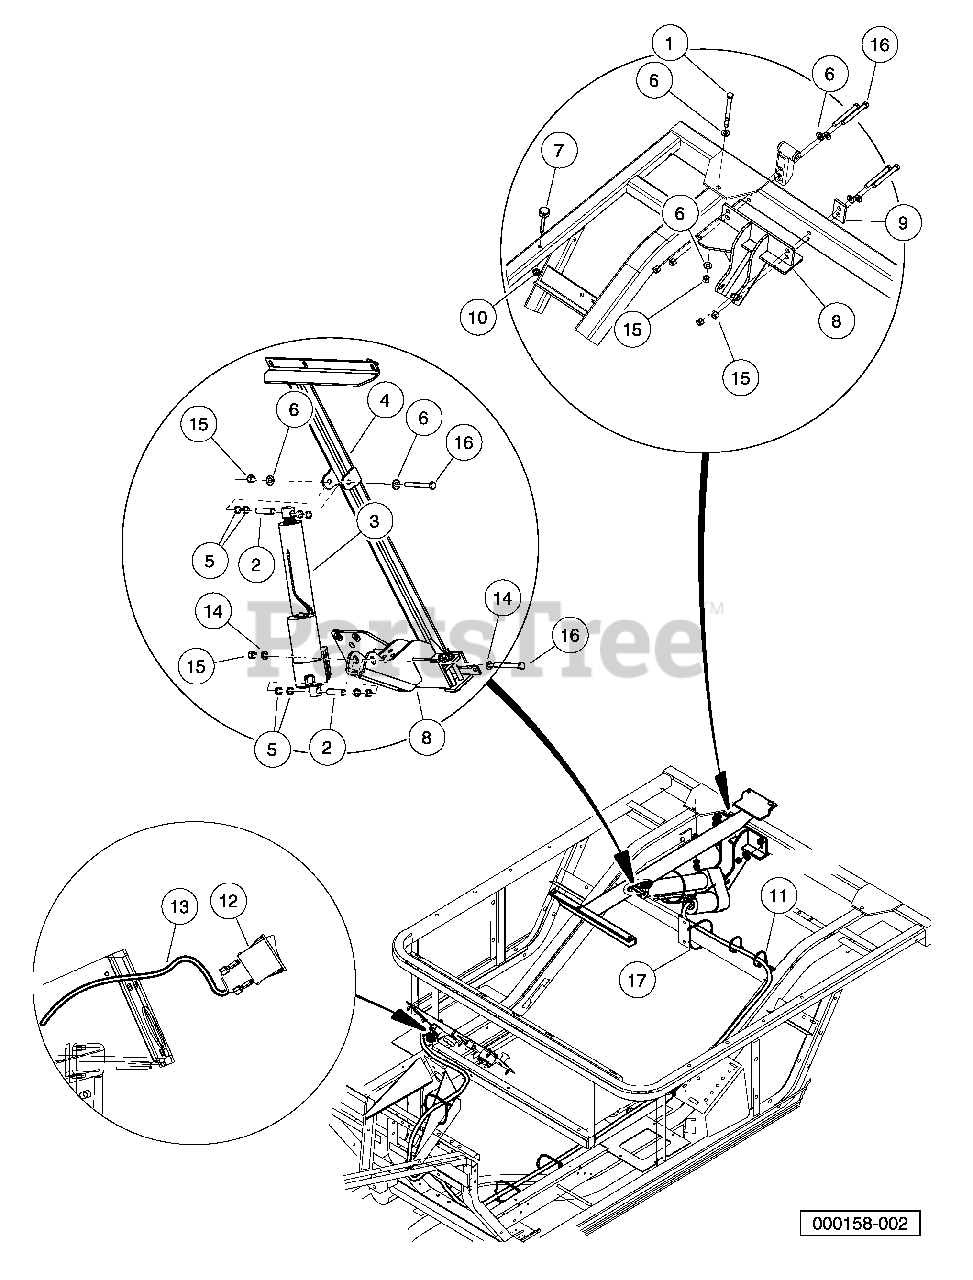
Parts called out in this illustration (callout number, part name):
1	Bolt, 3/8-16 X 4.25 Hex Head
2	Bushing Long
3	Actuator Assembly, Electric
4	Actuator Adapter
5	Body Spacer
6	Washer, 3/8 Type B Hard Flat
7	Bumper, Bed, Mtg, Front
8	Weldment, Bracket, Actuator
9	Plate, Back
10	Lock Nut, Flg M8 X 1.25 Nylon
11	Tie Wrap, 8.00" With Mount
12	Switch, Rocker, Spring Return, Bed Lift
13	Harness, AWD Bedlift
14	Washer, Lock, Hel Sp 3/8 Reg
15	Locknut, 3/8-16 Hex
16	Screw, 3/8-16 X 3.375 Hex Cap
17	Tie Wrap, 8" Nylon
